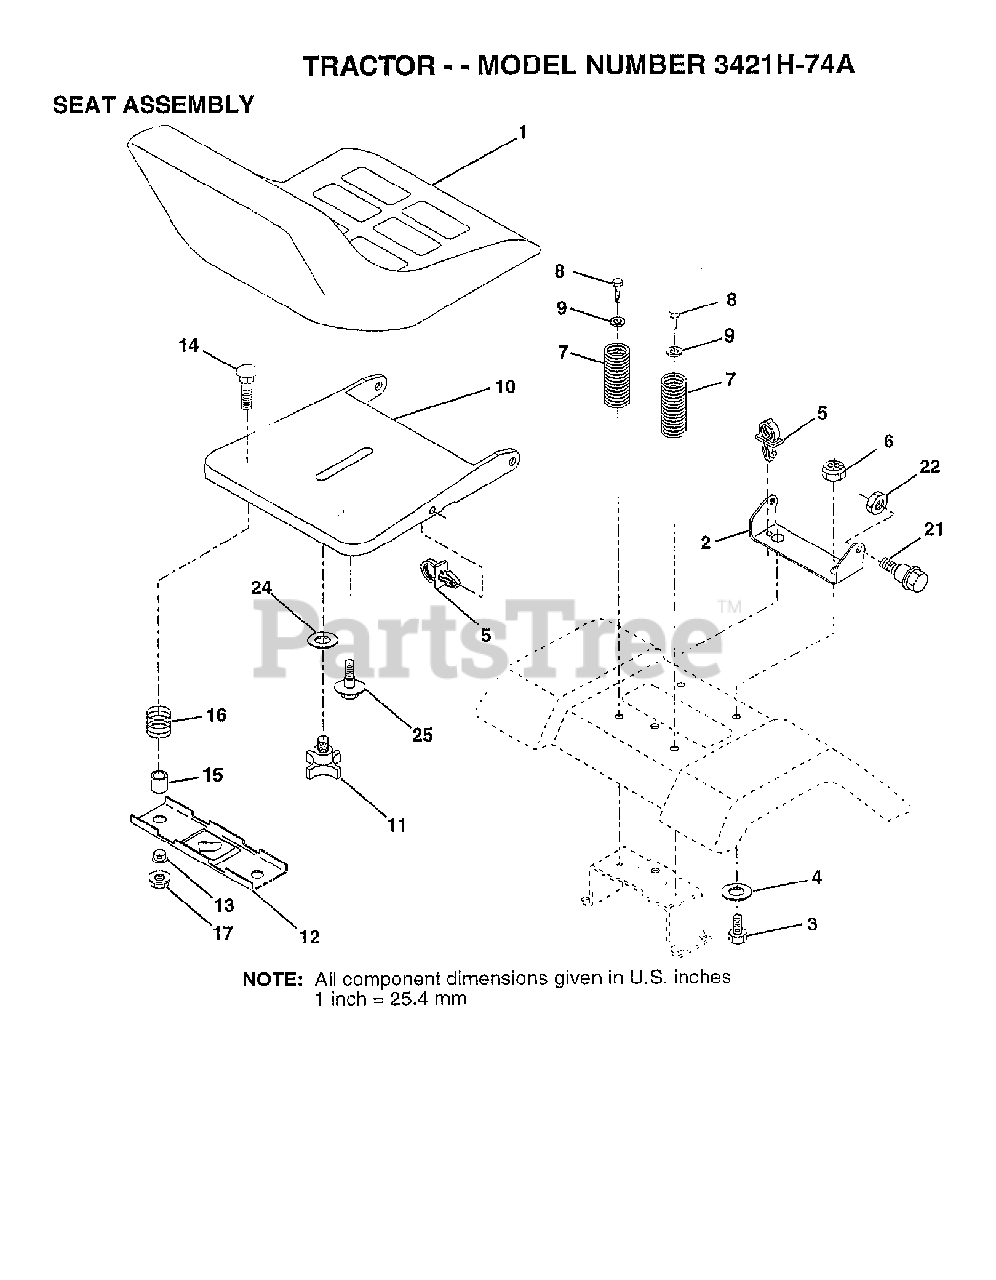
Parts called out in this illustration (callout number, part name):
2	BRKT,SEAT PIVOT**
3	BOLT
4	WASHER PM
5	PUSH CLIP
6	NUT
7	SPRING COMPRESSION
8	SCREW GTV
12	BRKT SWITCH
14	BOLT CARRIAGE 1/4-20X1 3/8
15	SPACER SPLIT
16	SPRING COMPRESSED
17	NUT T
22	LOCKNUT
25	BOLT, SHOULDER**
